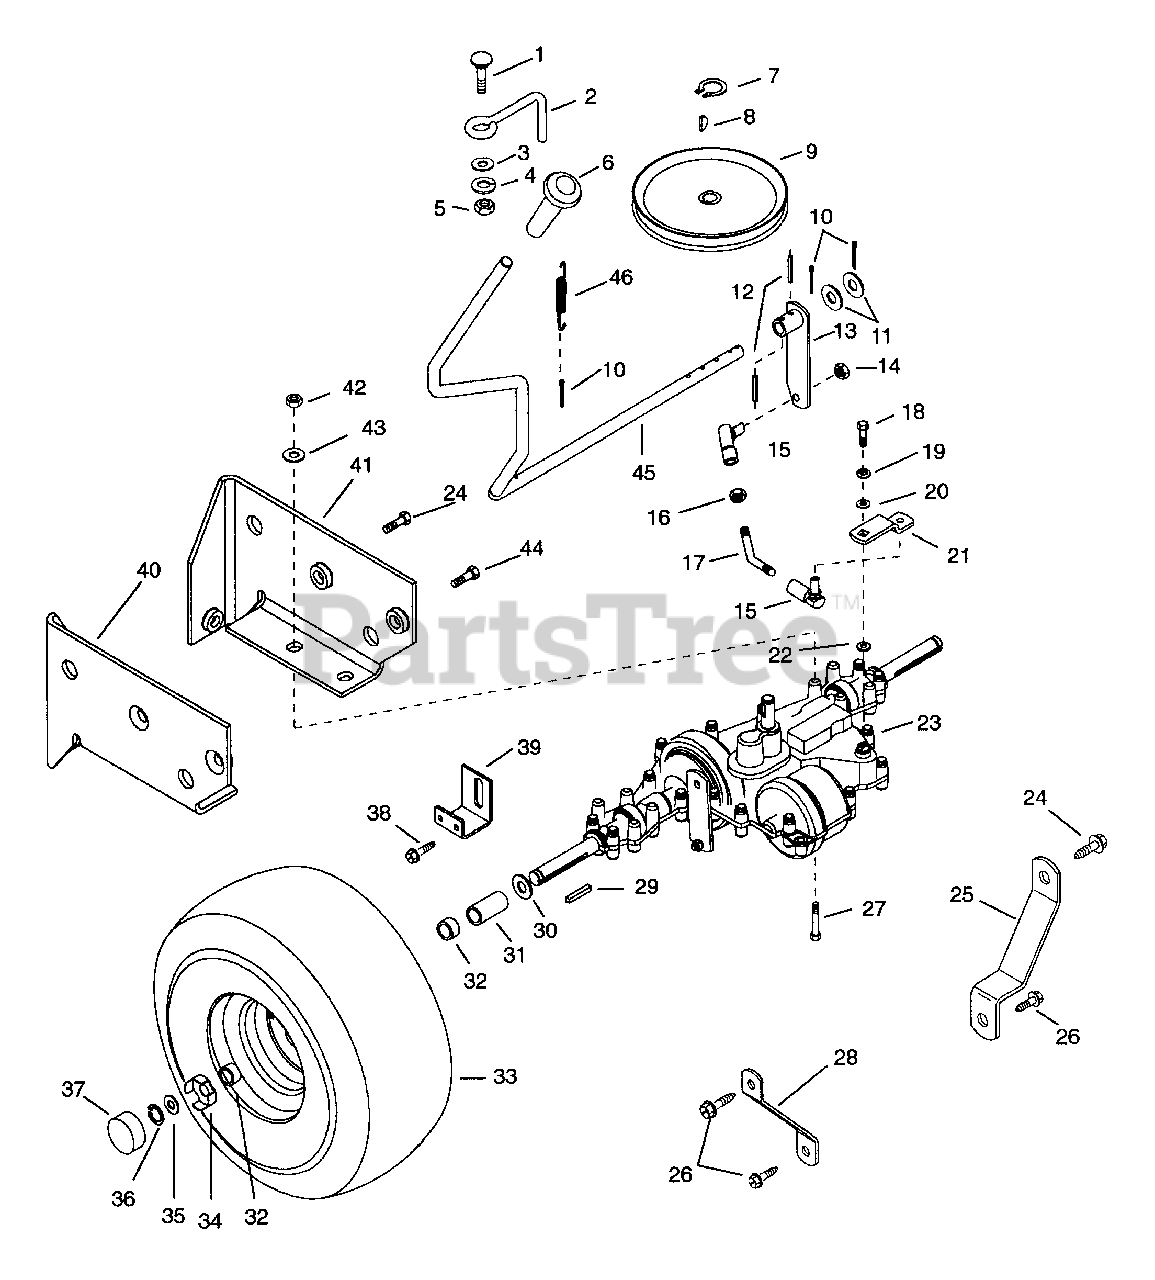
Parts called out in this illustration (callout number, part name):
1	BLT-RDHDSQNK.31-18X.75GR5SHTPL
2	FINGER - BELT
3	WSHR-FL-STL.344X.688X.065PL
4	WSHR-LK .312X.097 PL HVY
5	NUT-HEX .312-18
7	RG-RTNG-EXT .625X.035
8	KEY-WDRF .188X.75X.313 SAE 9
9	PLY-TRANS 7.00X.626
10	PIN-COTR .12X1.0 PL
11	WSHR-FL-STL .520X.827X.062 YZ
12	PIN-GRV .188X1.25 TP A
13	ARM & HUB
14	NUT-LK-CTR .312-24 PL
15	BALL JOINT- SNAP IN
16	NUT-JAM .312-24 PL
17	LINK - SHIFT
18	BLT-HEX .25-28X.75 PL GR8
19	WSHR-LK .250X.077 HVY PL
20	WSHR-FL-STL .328X1.0X.094 PL
21	ARM - SHIFT 6 SPD
22	WSHR-FL-STL .505X1.000X.062
23	TRANSAXLE - GEAR 6 SPEED MST
24	SCR-TAP .375-16X.75 HWH PL TR
25	STRAP - TORQUE,LH 6 SPD
26	SCR-TAP .312-18X.75 HWH PL TR
27	BLT-HEX .31-18X2.50 PL GR5
28	TORQUE STRAP
29	KEY-SQ .188X2.0X.188 SAE 8630
30	WSHR-FL-STL .755X1.375X.062 PL
31	BSHG-SLV .750X1.125X1.062
32	SPACER .760X1.000X.575
33	T/WHL ASSY 20X8.00-8
34	SPINDLE CUP
35	WSHR-FL-STL .755X1.375X.062 PL
36	RG-RTNG-EXT .750X.050
37	HUB CAP
38	SCR-TAP .312-18X.50 HWH TR BL
39	SHIFT GUIDE BRACKET
40	MOUNT - TRANS. RH
41	MOUNT - TRANS. LH
42	NUT-LK-TOP .312-18 GR C PL
43	WSHR-FL-STL .328X.875X.062 PL
44	SCR-TAP .375-16X .50 HWH PL TR
45	LEVER - SHIFT
46	SG-TENS .063X.44X1.56
